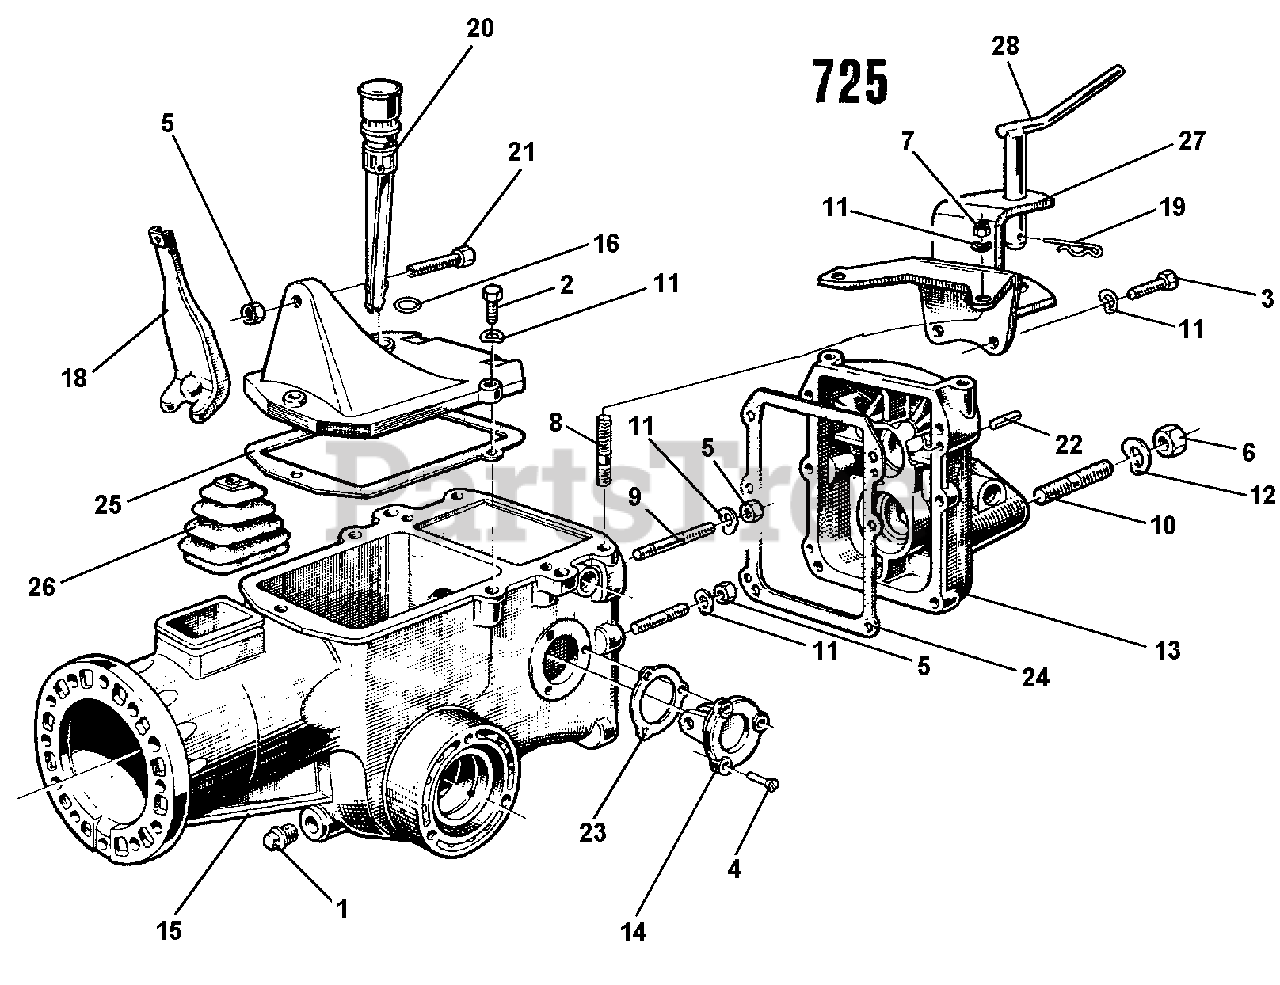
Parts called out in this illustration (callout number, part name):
1	PLUG 1/4 GAS
2	SCREW TE M8 X 25
3	SCREW M8 X 25
4	SCREW TSV M6 X 16 UNI 260-S
6	STUD M8 X 38 X 14 X 20
7	NUT, SELF LOCKING M8
8	STUD M8 X 46 X 16 X 16
9	STUD M8 X 58 X 16 X 16
10	STUD 56XM12X1.25X26XM12X228G
11	WASHER, LOCK 8.4
12	WASHER, LOCK 13
13	HOUSING COVER
14	FLANGE, REVERSE SPEED
15	CASING 5 SPEEDS GEARBOX
16	RUBBER RING
18	CLUTCH LEVER
20	CAP, WITH MEASURING ROD
21	SCREW ADJUSTING M8
22	PARALLEL PIN D 6 X 20
24	GASKET, COVER
25	GASKET, COVER
27	TOW COUPLING
